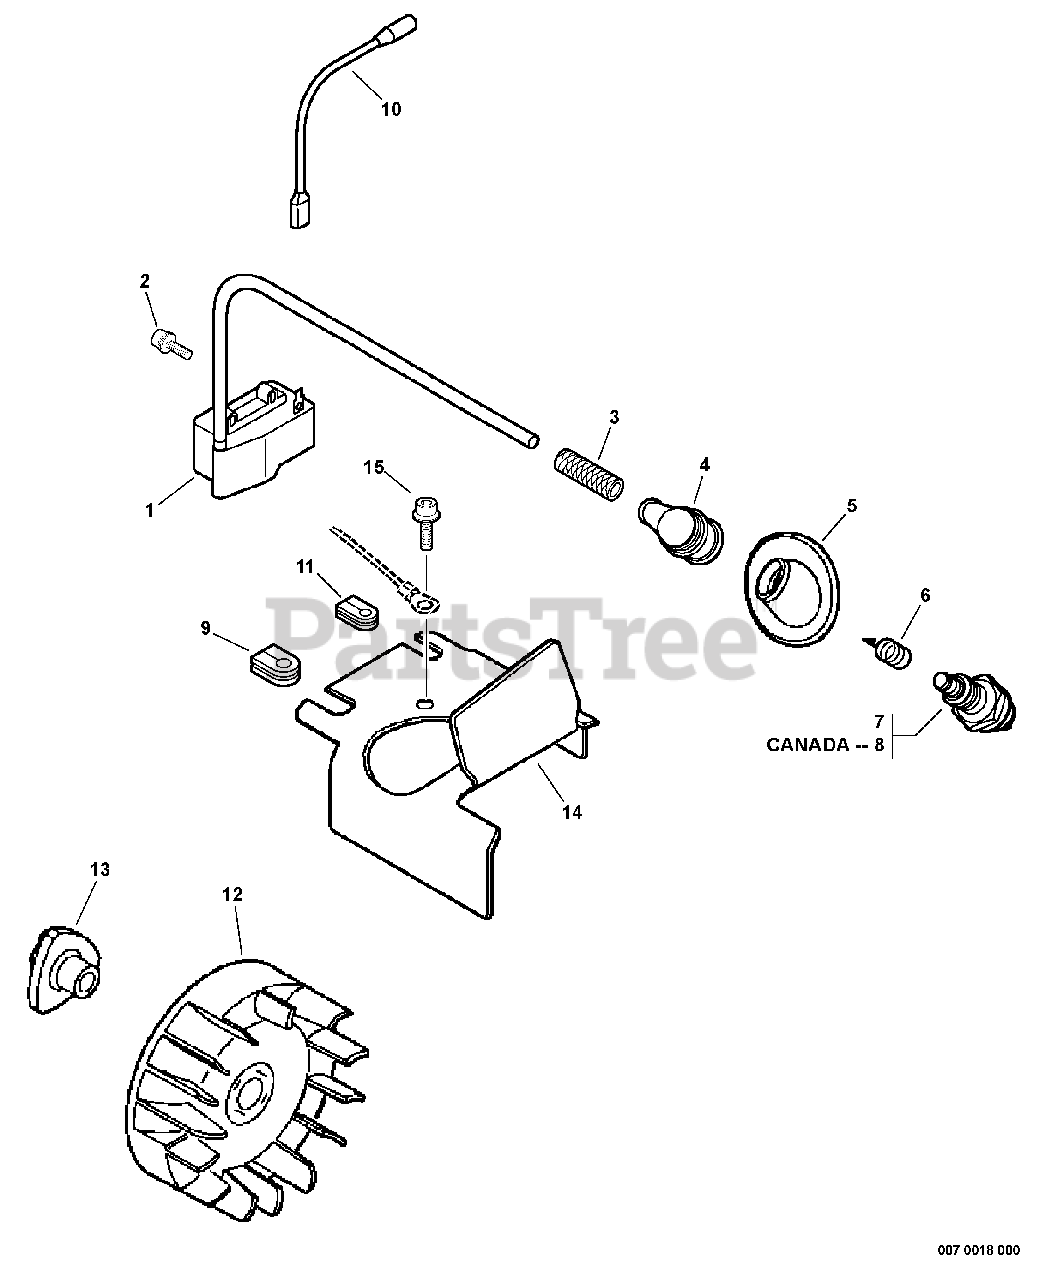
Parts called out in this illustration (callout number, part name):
1	COIL, IGNITION
2	SCREW - 4X20
3	INSULATOR
4	CAP, SPARK PLUG
5	COVER, DUST
6	TERMINAL, SPARK PLUG CAP
7	SPARK PLUG -- BPM-8Y
8	SPARK PLUG -- BPMR-8Y
10	LEAD - IGNITION
12	FLYWHEEL
13	HUB, FAN
14	SHIELD, CYLINDER
15	SCREW - 5X8
